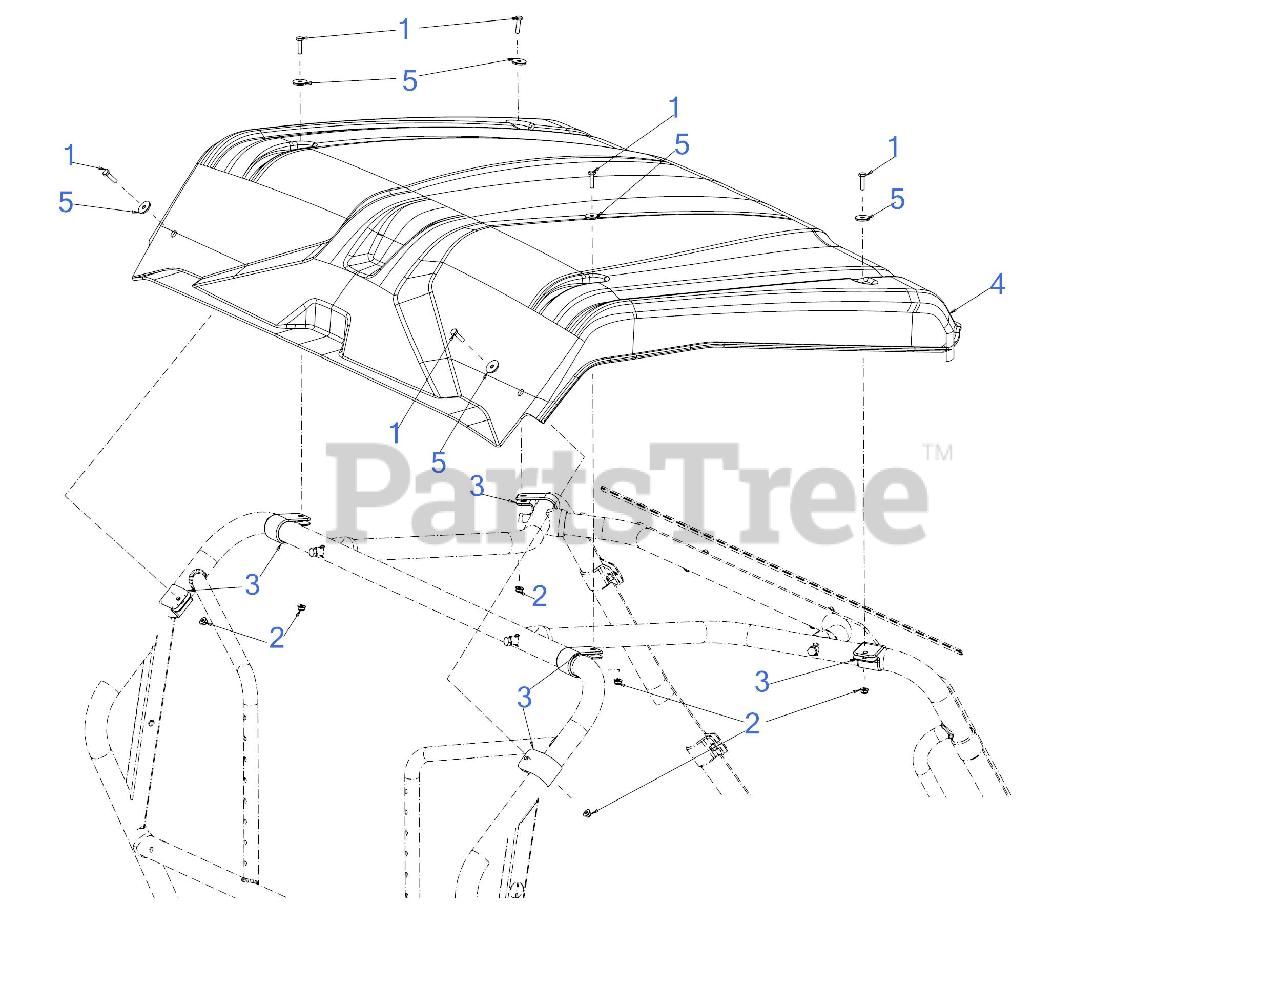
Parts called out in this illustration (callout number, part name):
1	SCREW 1/4-20 X1.00 GR5
2	FLANGE LOCK NUT
5	FLAT WASHER .275 X 1.00 X .103
